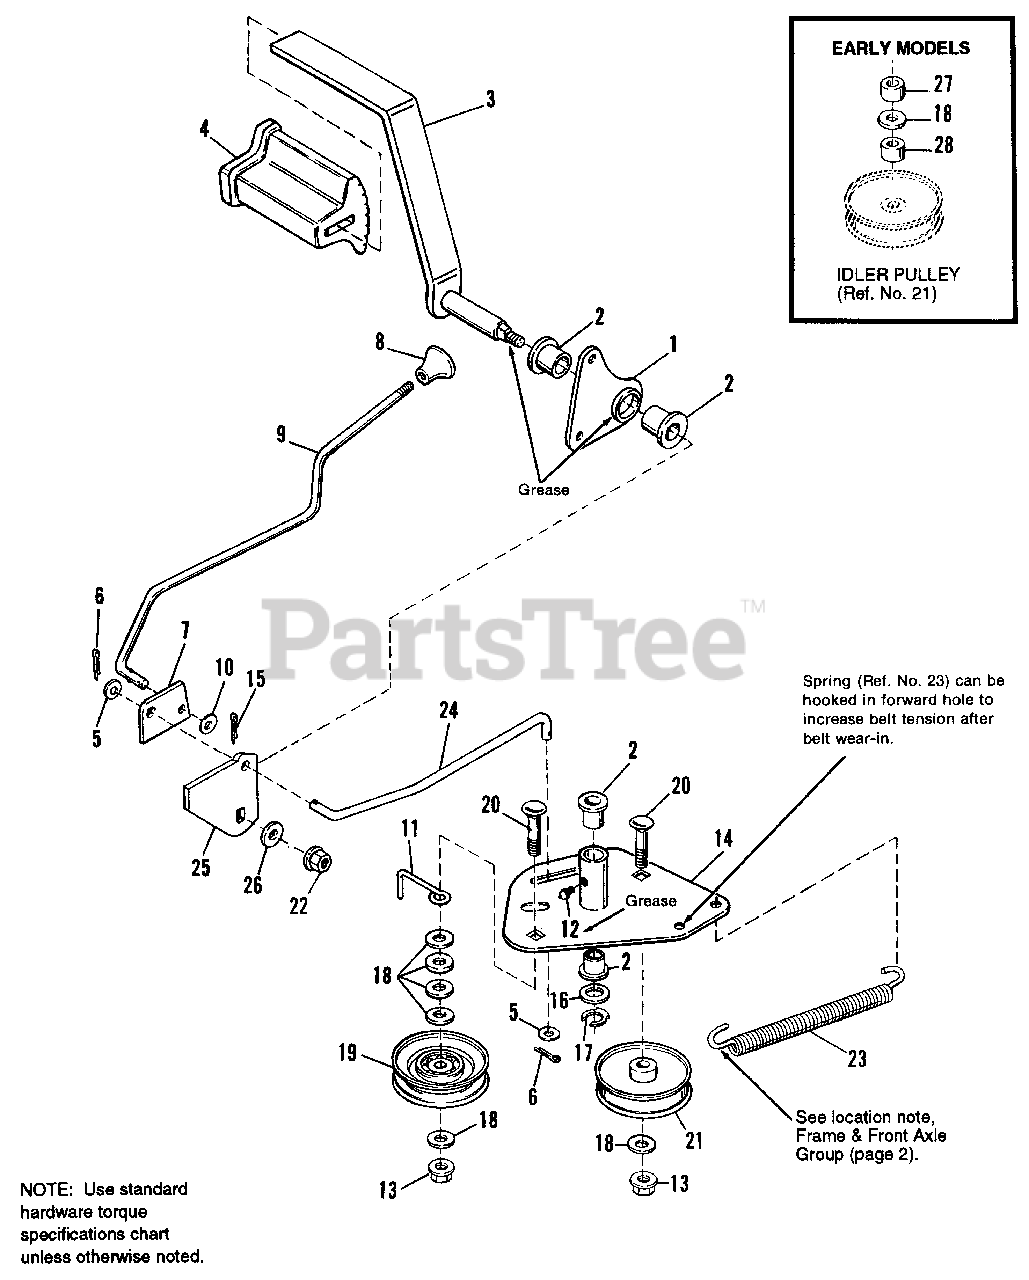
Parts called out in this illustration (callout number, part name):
2	BUSHING, Plastic
3	BRAKE PEDAL ASSY.
4	PAD, Foot Pedal
5	WASHER, Plain, 11/32
6	COTTER PIN
7	CAM, Parking Brake
8	KNOB, Plastic
9	ROD, Parking Brake
10	WASHER, Plain, 9/32
11	BELT STOP
12	FITTING, Grease
13	NUT, Flange, Whizlock, 3/8-16
14	ARM ASSY., Idler
15	COTTER PIN
16	WASHER, 5/8
17	KLIPRING, 5/8
18	WASHER, Plain, 13/32 (Qty. 8 on early model idler pulley)
20	CARRIAGE BOLT, 3/8-16 x 1-3/4
21	PULLEY, Idler
22	NUT, Hex ESNA, 3/8-16
23	SPRING, Drive
24	ROD, Clutch, 5/16 Dia.
25	ARM, Foot Pedal
26	WASHER
27	SPACER (Early models only)
28	SPACER (Early models only)
